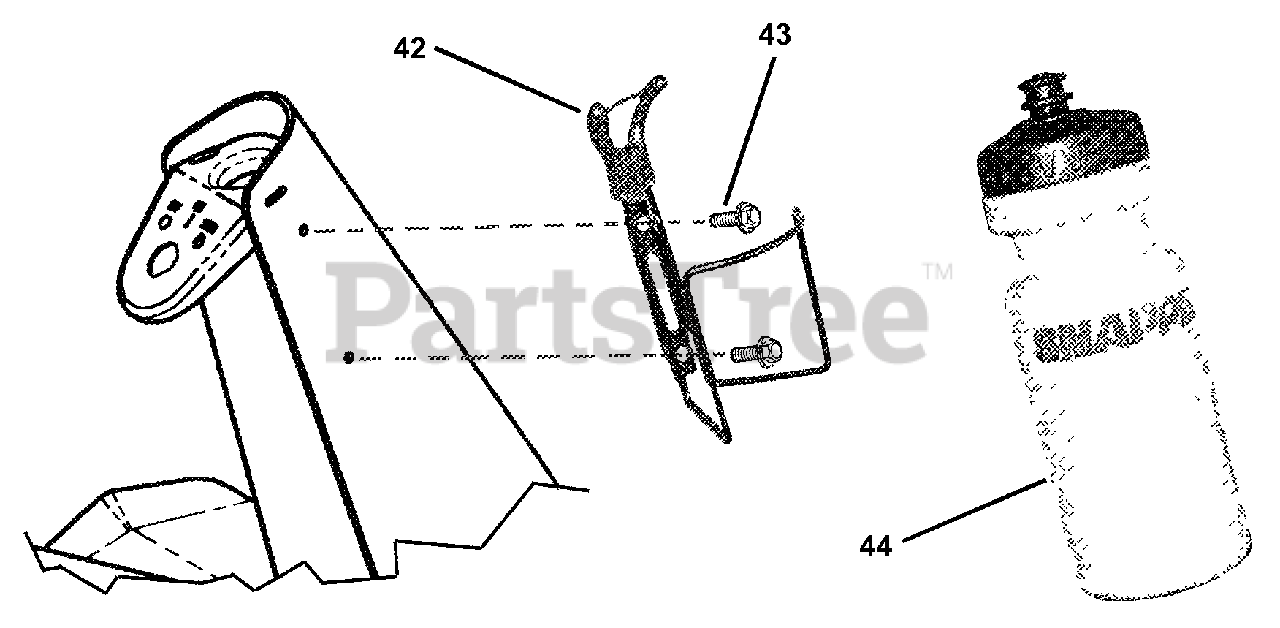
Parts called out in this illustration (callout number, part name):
42	HOLDER, Wire- Bottle
43	SCREW, #10-24 x 1/2" Hex Washer Self-Tap (Torx)
44	BOTTLE, Water
